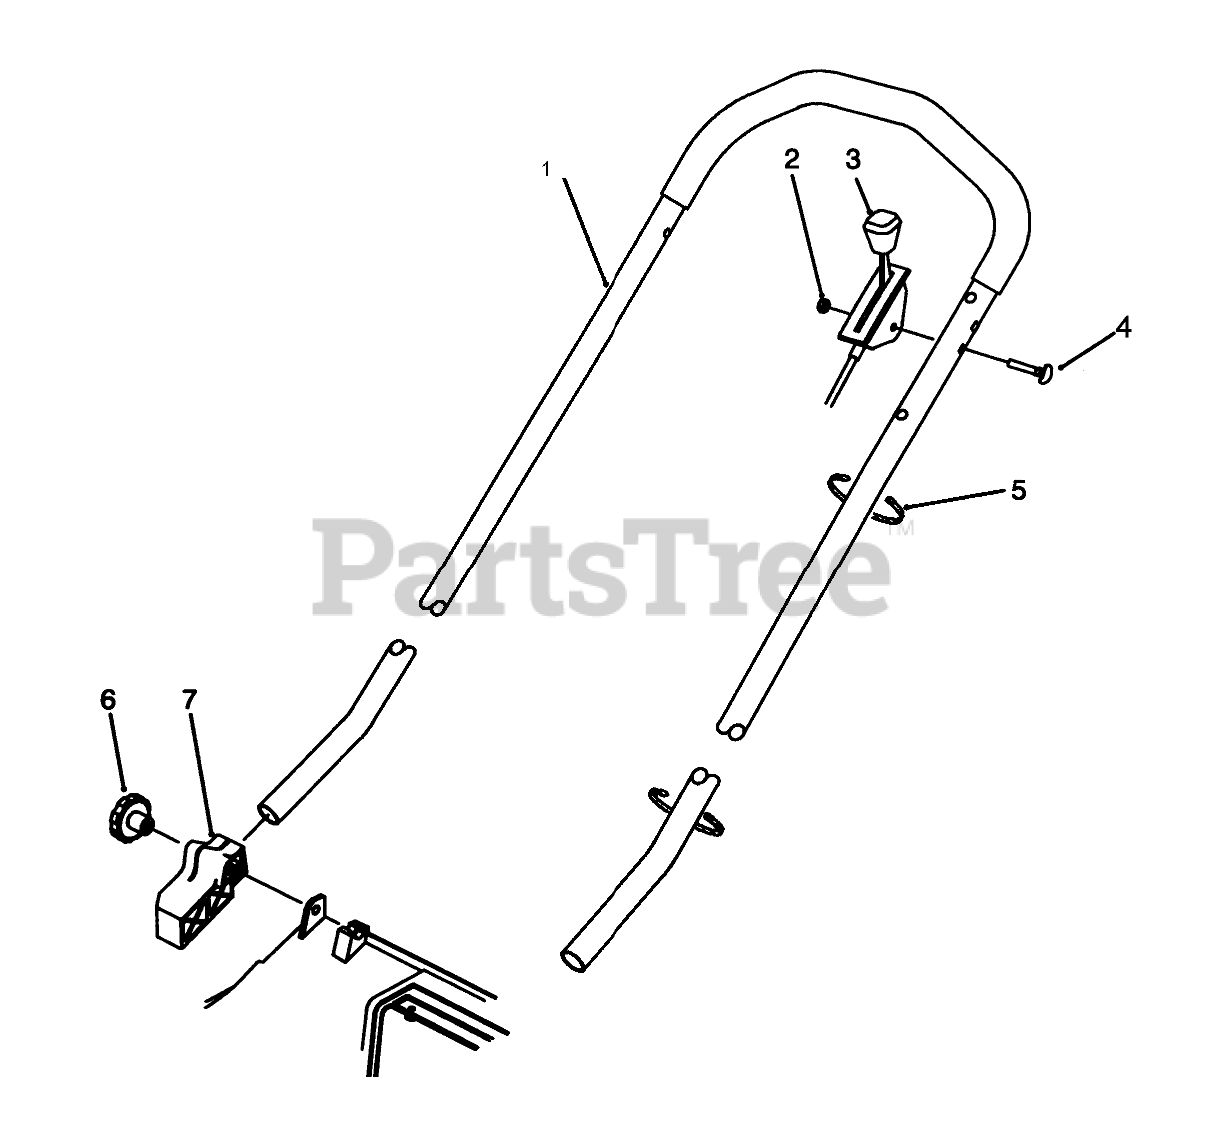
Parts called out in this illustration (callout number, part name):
1	Handle
2	NUT-LOCK, NI
3	THROTTLE CONTROL
4	SCREW-HANDLE
5	TIE-CABLE
7	MOUNT-HANDLE, RH
